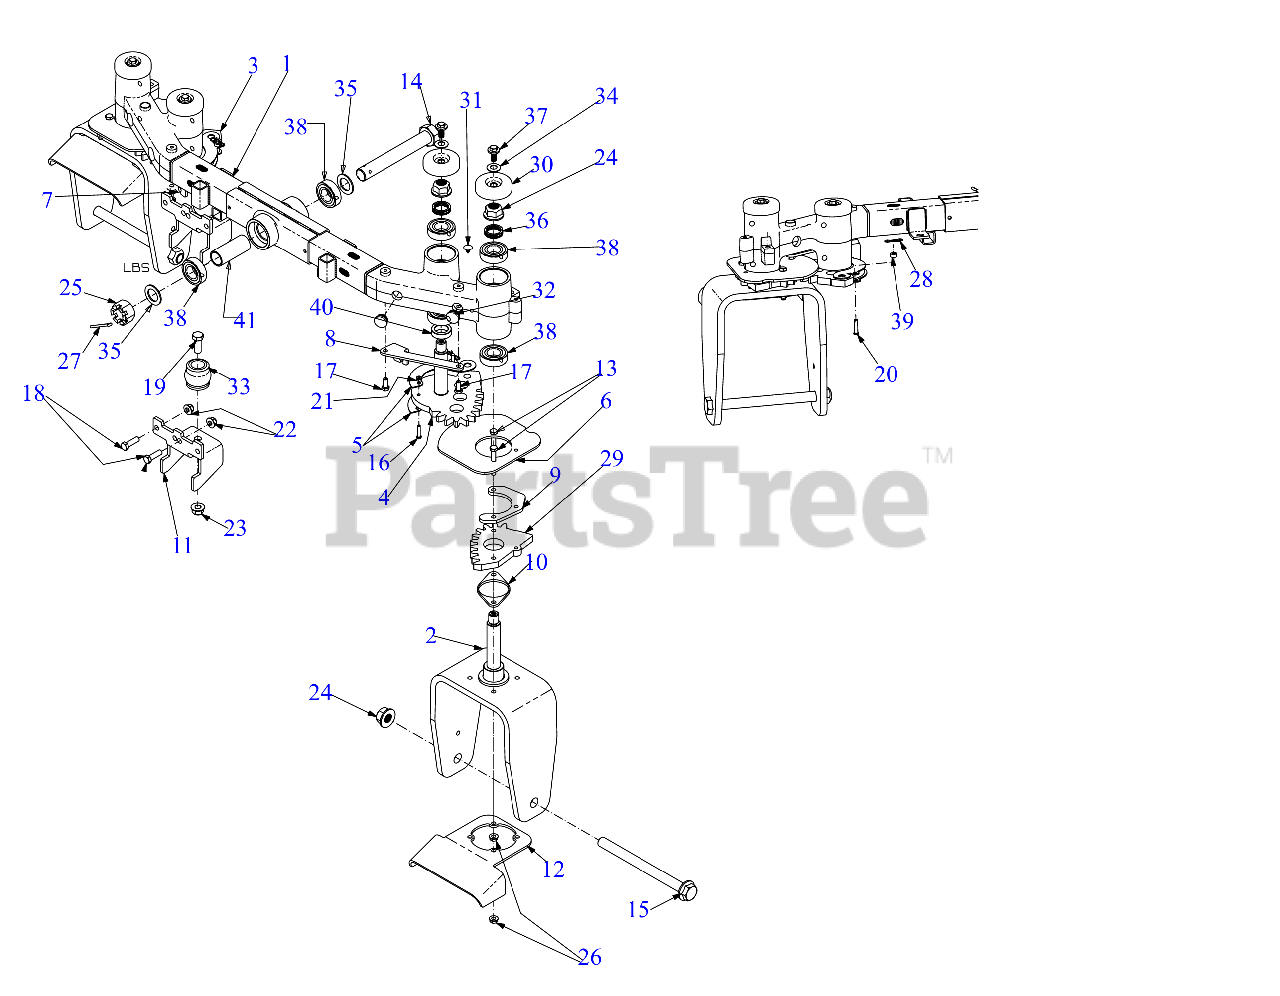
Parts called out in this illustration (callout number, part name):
4	RIGHT HAND STEERING GEAR ASSEMBLY
10	LOWER GEAR SPACER PLATE
13	HEX SCREW 5/16-18 x 2.25 GR5
14	HEX HEAD SCREW (1-14 x 7 GR5)
15	SCREW 3/4-16 x 9.00 GR5
16	SCREW #10-24 x 1.00 GR5.1
17	SCREW 5/16-18 x .750
18	SCREW 3/8-16 x 1.25 GR5
19	SCREW 1/2-13 x 1.25 GR5
20	CLEVIS PIN .25 x 1.00
24	FLANGE LOCK NUT 3/4-16 TOP LOCK
25	CASTLE NUT 1.0-14 GR5
26	HEX FLANGE NUT
27	COTTER PIN
28	BOW TIE COTTER PIN 1/4-5/16
29	STEERING GEAR YOKE
30	AXLE CAP 2.5"
31	RATCHET CLIP
33	AXIAL BUMPER
34	FLAT WASHER
35	BELL WASHER
36	WAVE WASHER
38	BALL BEARING (1.0 x 52 x 15)
41	SPACER 1.00 x 1.25 x 2.99
